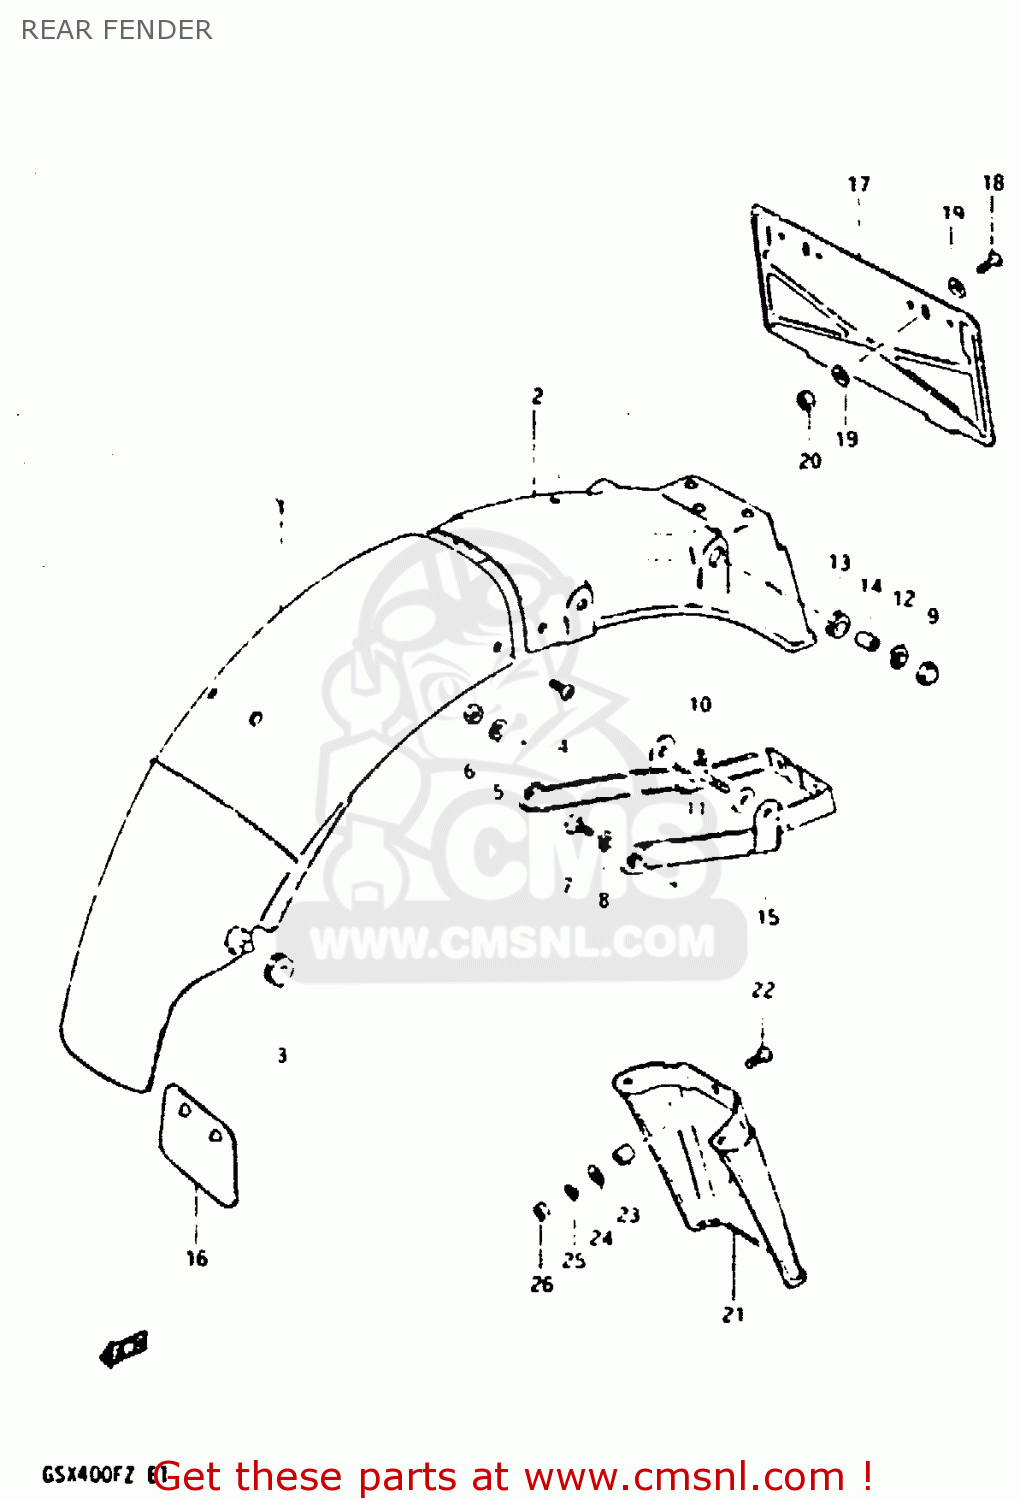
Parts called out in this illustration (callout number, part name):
1	BODY,RR FENDER FR
2	BODY, REAR FENDER REAR
3	CUSHION
4	SCREW
5	WASHER (5.5X16X1.2)
6	NUT
7	BOLT, UPPER
8	LOCK WASHER
9	NUT
10	BOLT
11	WASHER
12	LOCK WASHER
13	CUSHION
14	SPACER (8.2X12X7.5)
15	REINFORCEMENT, REAR FENDER
16	GUIDE,RR FENDER MUD
17	HOLDER,RR LICENSE PLATE
18	BOLT
19	WASHER
20	NUT
